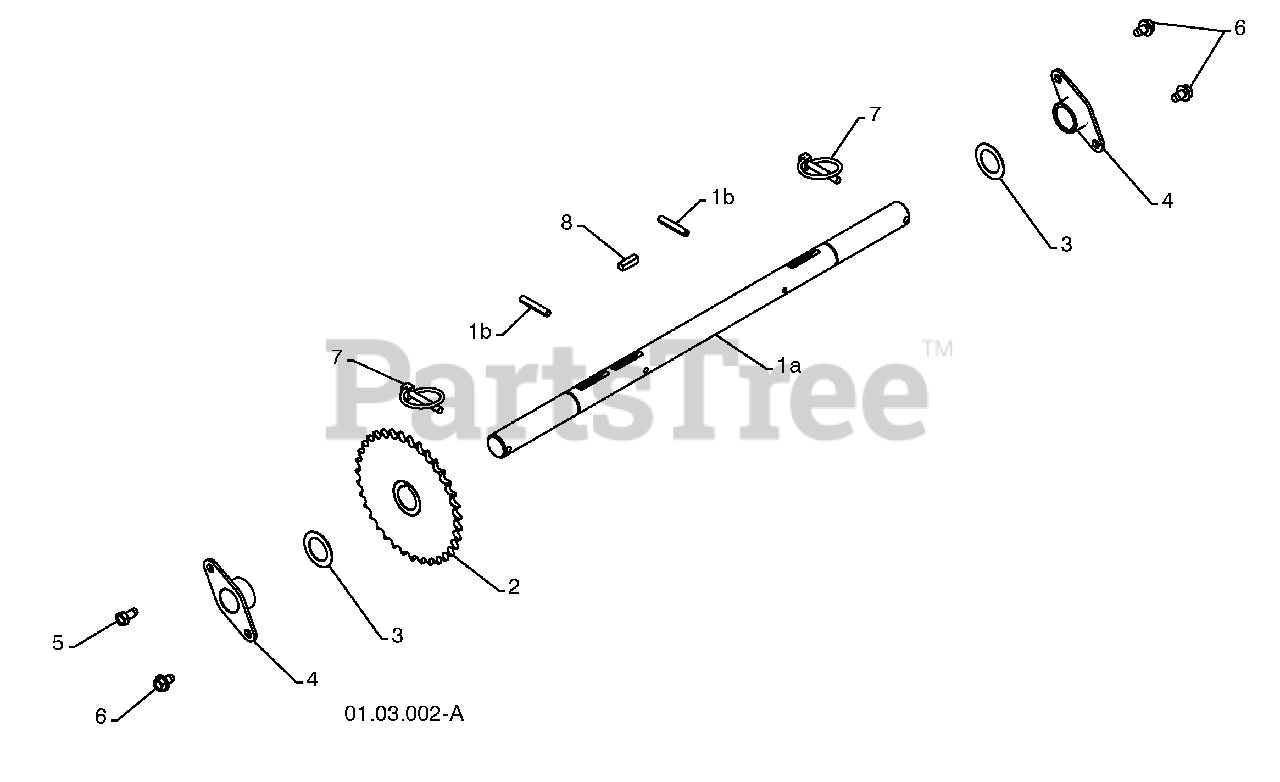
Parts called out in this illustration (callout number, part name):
1	AXLE ASSEMBLY (assy of 1a,1b)
2	SPROCKET
3	THRUST WASHER
4	BEARING
5	SCREW 5/16-18 X .625
6	SCREW 5/16-18 X .500
7	KLIK PIN 1/4 X 1.50
8	SQUARE KEY
